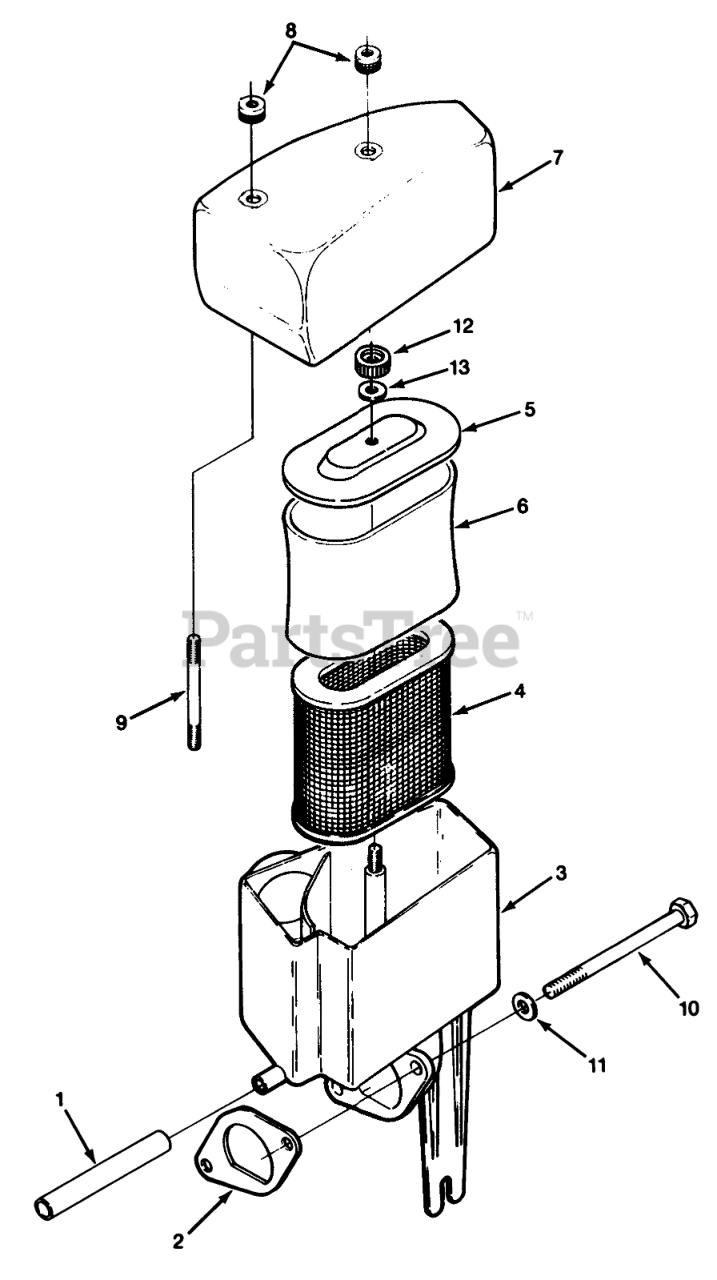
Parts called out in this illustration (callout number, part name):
1	HOSE-BRH 3/8"IDX91MM
2	Gasket
3	Adapter
4	Element
5	COVER-ELEMENT
6	WRAPPER-ELEMENT
7	Air Cleaner Cover
8	KNOB M6
10	HHCS-M8 X 100MM
11	Nut-M8
13	GROMMET
